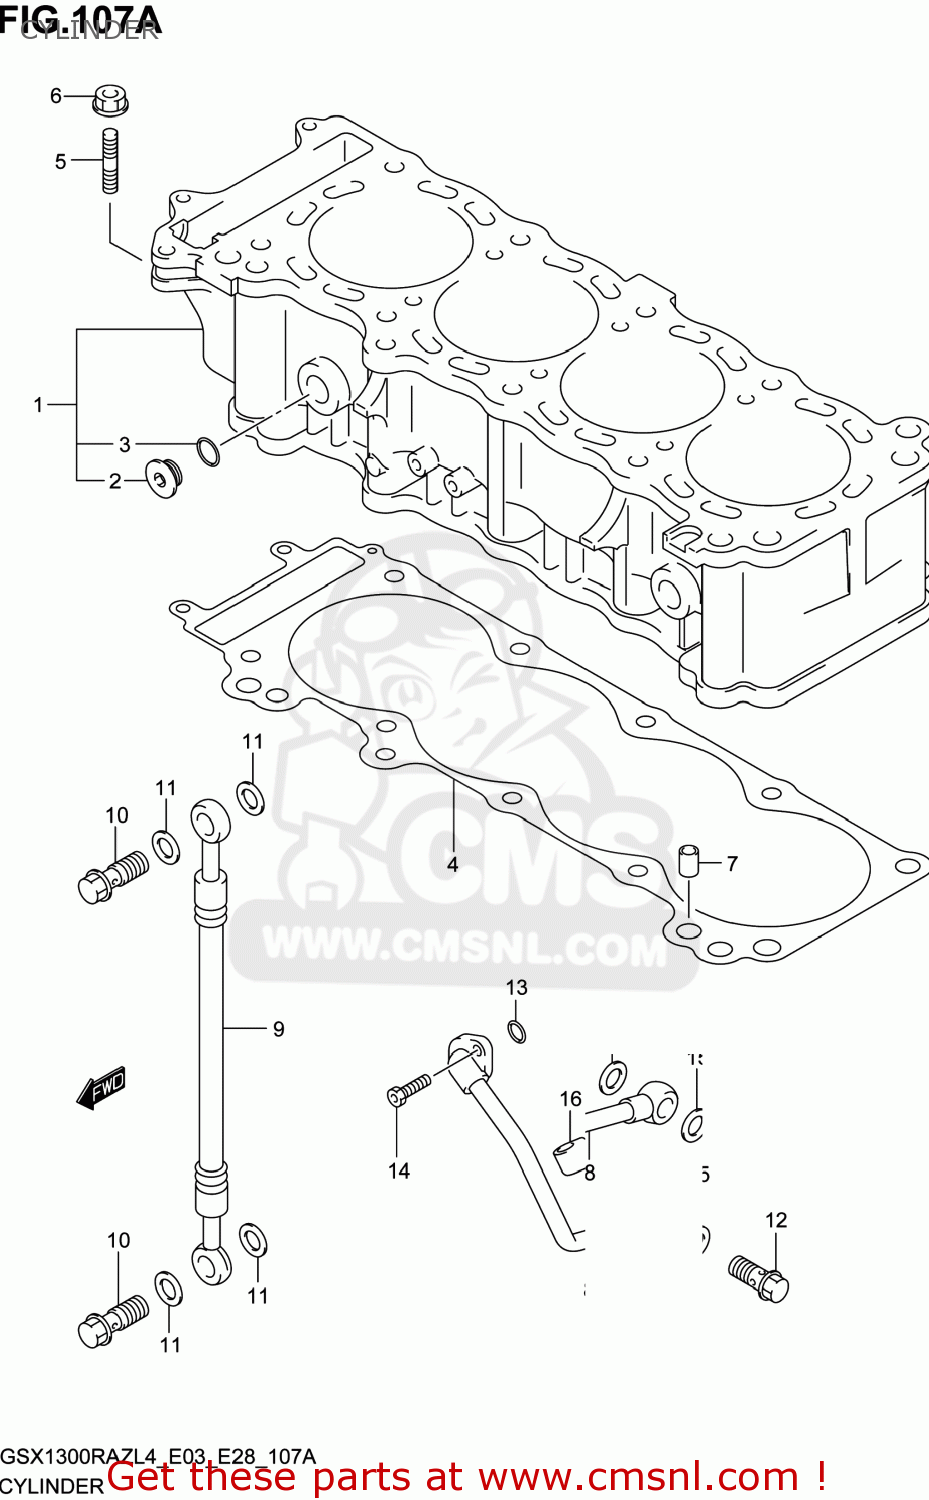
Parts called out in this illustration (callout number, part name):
1	CYLINDER
2	PLUG,WATER JACKET
3	O RING(D:3.1,ID:19.4)
4	GASKET,CYLINDER (NAS)
5	BOLT,STUD
6	NUT
7	PIN
8	PIPE,CRANKCASE OIL
9	HOSE,CYLINDER HEAD OIL
10	BOLT UNION
11	GASKET(10.1X16X1) (NAS)
12	BOLT UNION
13	O RING(D:2.4,ID:11.8)
14	BOLT(6X16)
15	GASKET(14X20X1.5) (NAS)
16	CUSHION,CRANKCASE DIL PIPE
